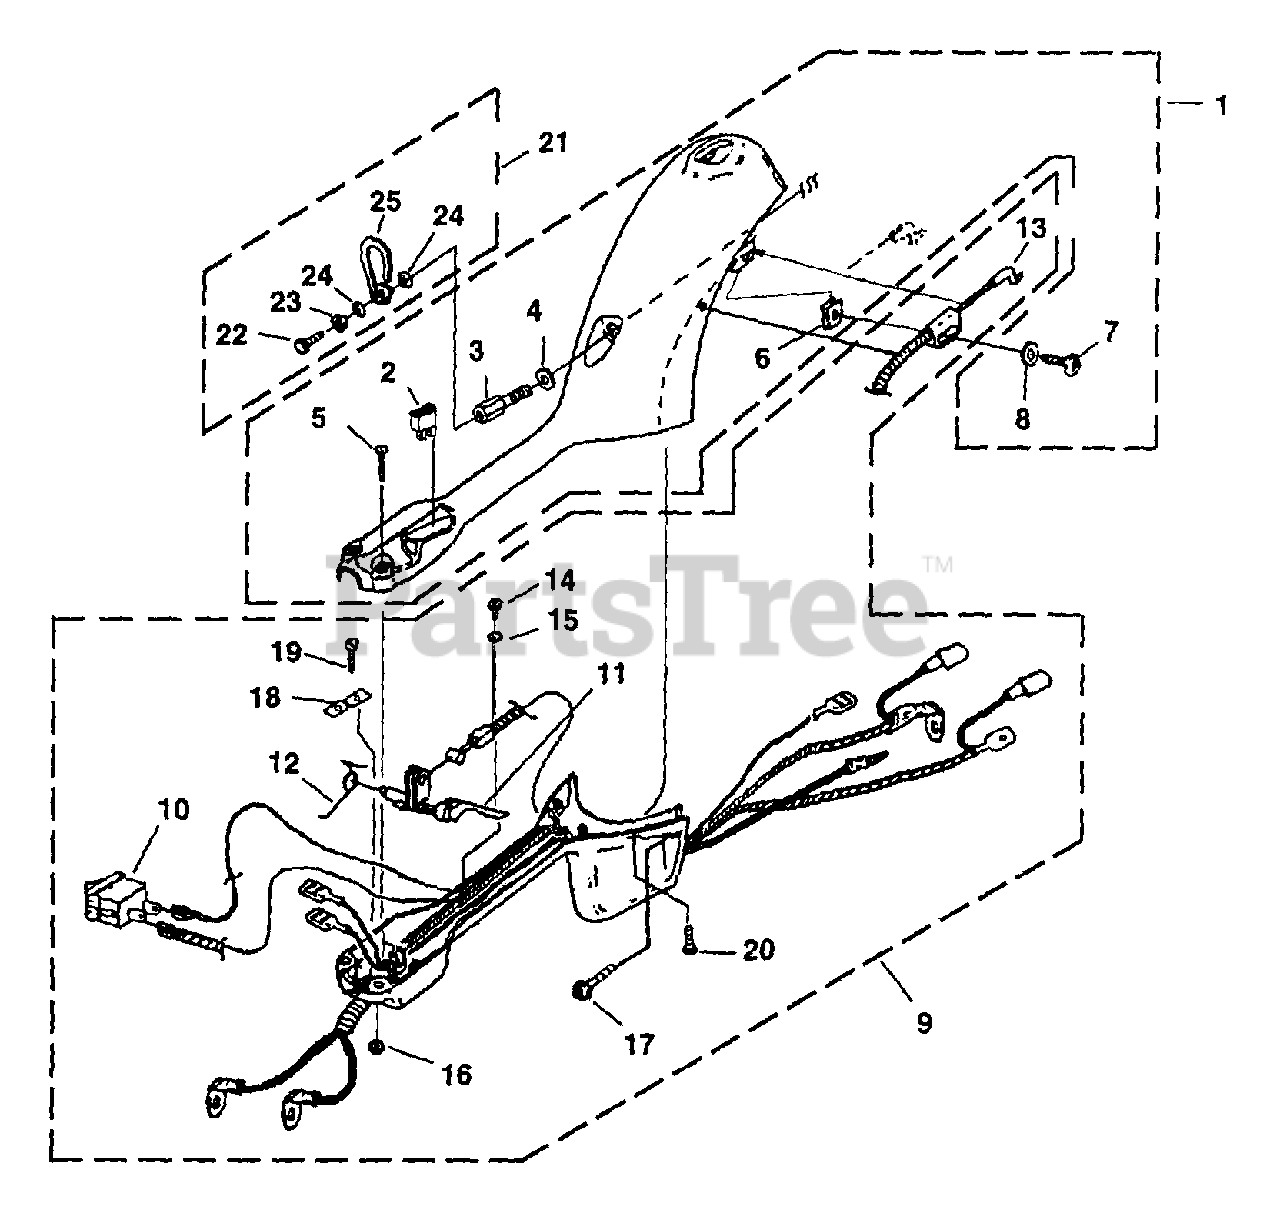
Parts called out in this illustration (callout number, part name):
1	CLUTCH HOUSING (Top)
2	SWITCH-Start
3	SCREW-Adaptor
5	SCREW-Truss Hd. (10-24 x 1 7/8")
6	NUT-Tinnerman
7	SCREW-Socket Hd.
8	WASHER-Flat
9	CONTROL HANDLE ASSEMBLY
10	SWITCH-Rocker (STOP)
11	Trigger
12	SPRING-Torsion
13	CABLE-Throttle
14	SCREW-Thread Form (4-20 x 1/4")
16	NUT-Hex (10-24)
17	SCREW-Torx Truss Hd (10-24 x 3 1/4")
18	RETAINER
19	SCREW-Thread Form (6-20 x 1/2")
20	SCREW-Thread Form (10-14 x 1/2")
21	HANGER KIT
22	SCREW (10-32 x 1/2")
23	WASHER-Lock
